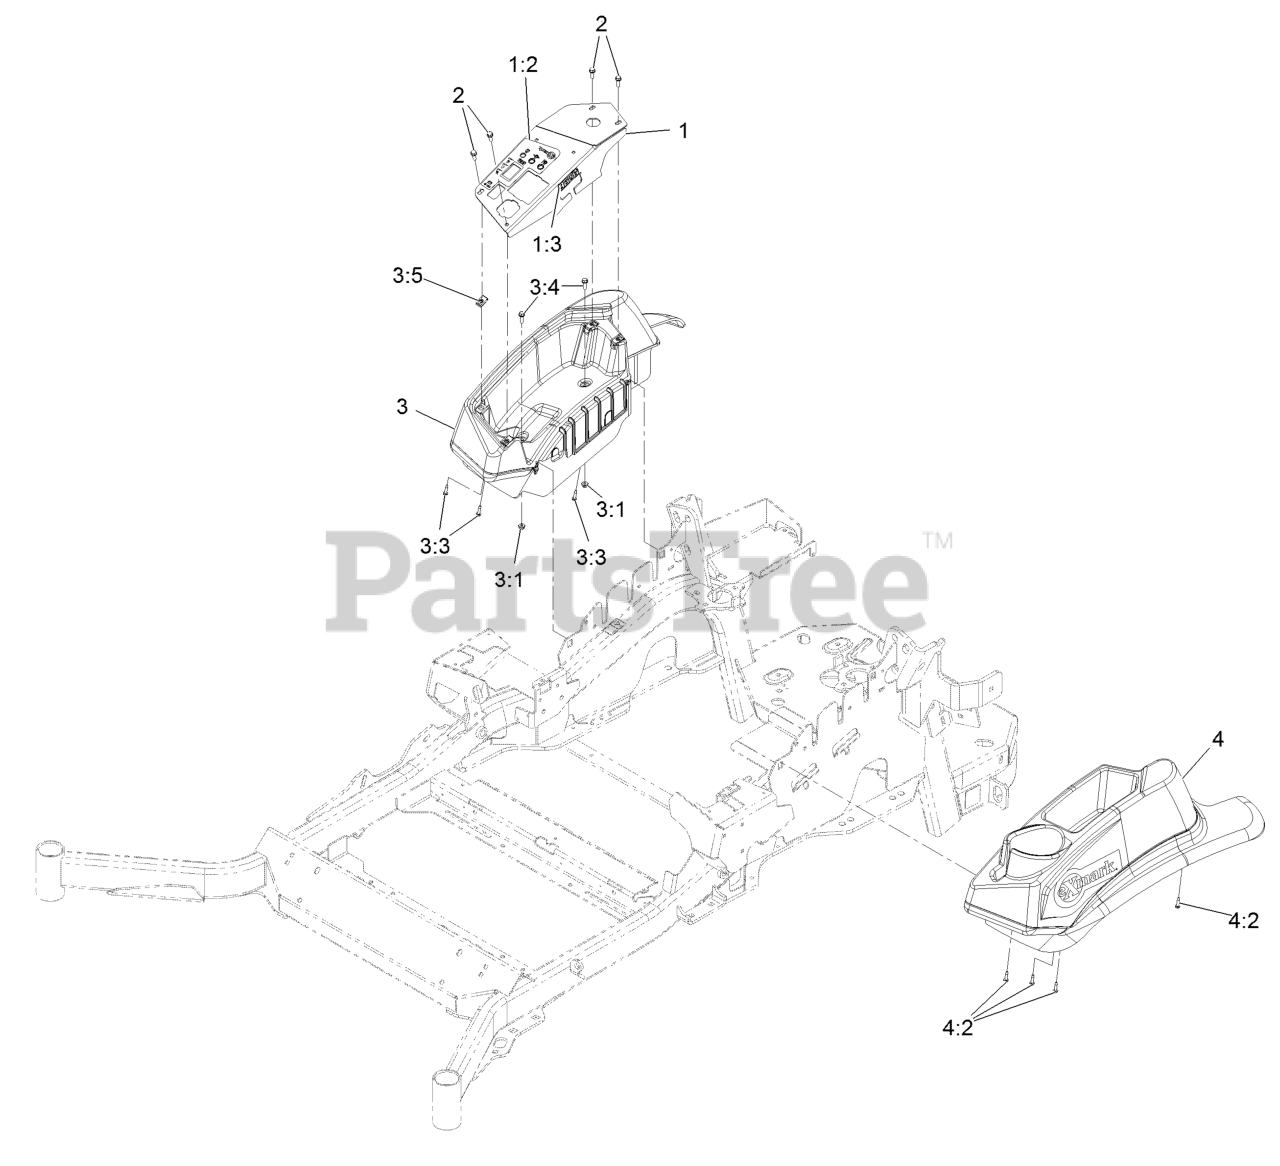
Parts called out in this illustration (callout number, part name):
1	CONTROL PANEL W/DECAL
1:2	DECAL-CONSOLE RED
1:3	DECAL-FUSES
2	SCREW-HWH
3	CONSOLE,RH NARROW ASM
3:3	SCREW,THD FORM,HWH
3:4	SCREW-HWH
3:5	Nut-Retainer-Panel 1/4-20
4	CONSOLE.LH NARROW ASM
4:2	SCREW,THD FORM,HWH
